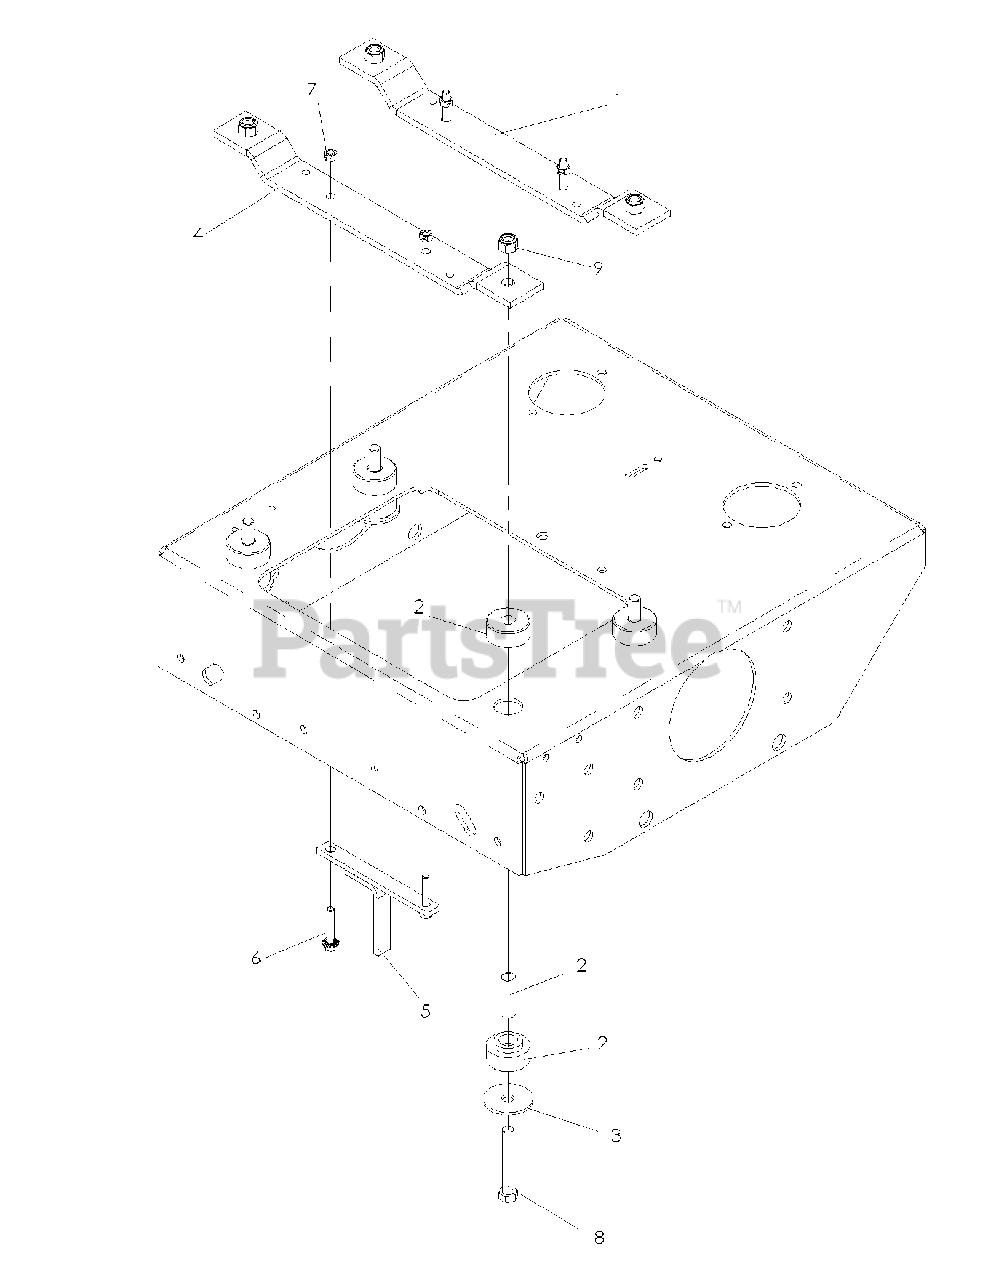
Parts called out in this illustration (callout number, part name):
1	ENGINE MOUNT
2	ISOLATORS
3	ISOLATOR WASHER
4	STRAP, ISO, REAR
5	CLUTCH TIE DOWN
6	HCS 5/16-18 X 1-3/4 SERATED
7	NUT 5/16C CENTERLOCK
8	HCS 1/2C X 3 1/4
9	NUT 1/2-13 HEX NYLOC ZD
